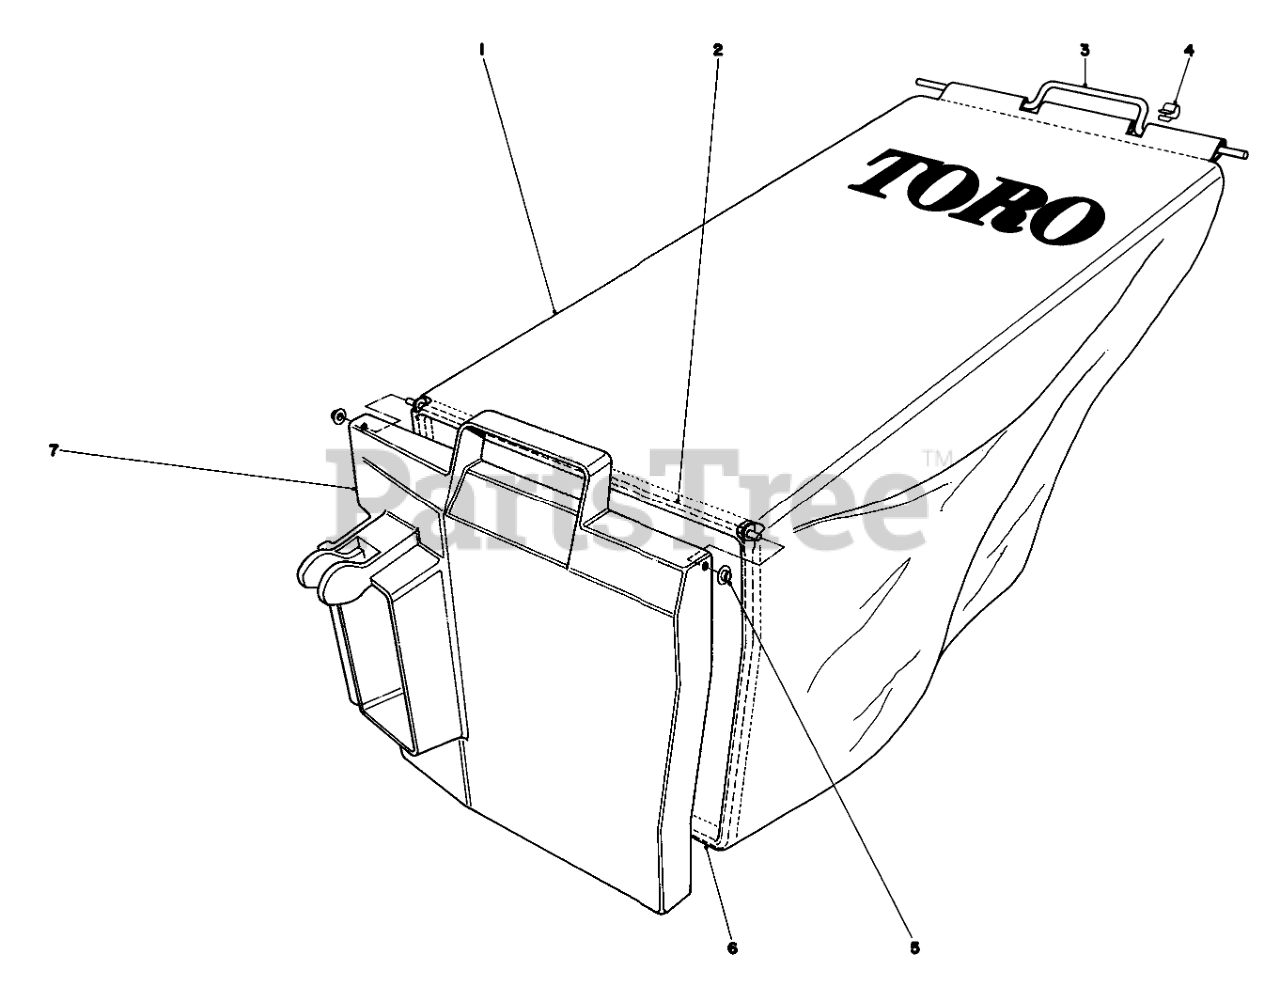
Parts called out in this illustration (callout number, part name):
2	HINGE
3	Handle Bag
4	Clip Bag Handle
5	Nut-Push
6	Frame Bag
7	Door-Bag
